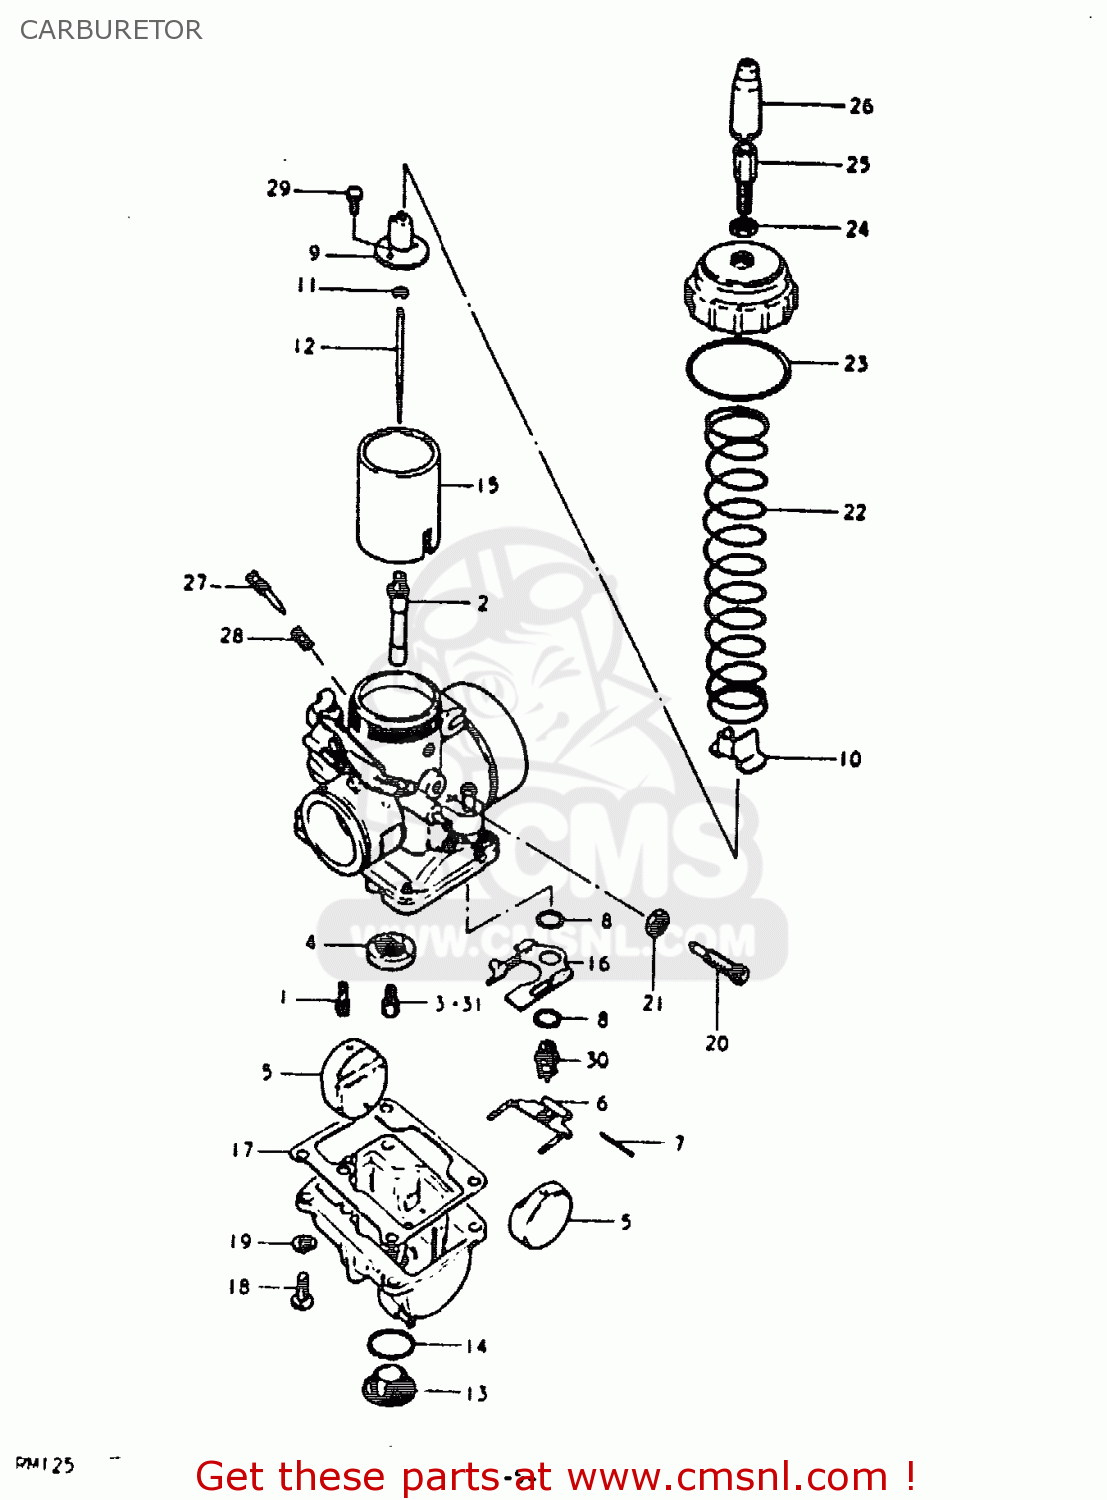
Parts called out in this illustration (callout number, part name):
1	JET
2	JET,NEEDLE
3	JET
4	RING,MAIN JET FIXING
5	FLOAT
6	ARM,FLOAT
7	PIN,FLOAT
8	GASKET,MAIN JET HOLDER (NAS)
9	CONNECTOR
10	COVER,HOLDER
11	CLIP
12	NEEDLE JET
13	PLUG
14	GASKET,DRAIN PLUG
15	VALVE,THROTTLE
16	PLATE
17	GASKET,FLOAT CAHMBER (NAS)
18	SCREW
19	LOCK WASHER
20	ADJUSTER
21	NUT
22	SPRING,THROTTLE VALVE RETURN
23	O-RING,MIXING CHAMBER
24	NUT
25	ADJUSTER,CABLE
26	CAP
27	SCREW,PILOT AIR
28	SPRING
29	SCREW
30	VALVE ASSY,NEEDLE
31	JET
